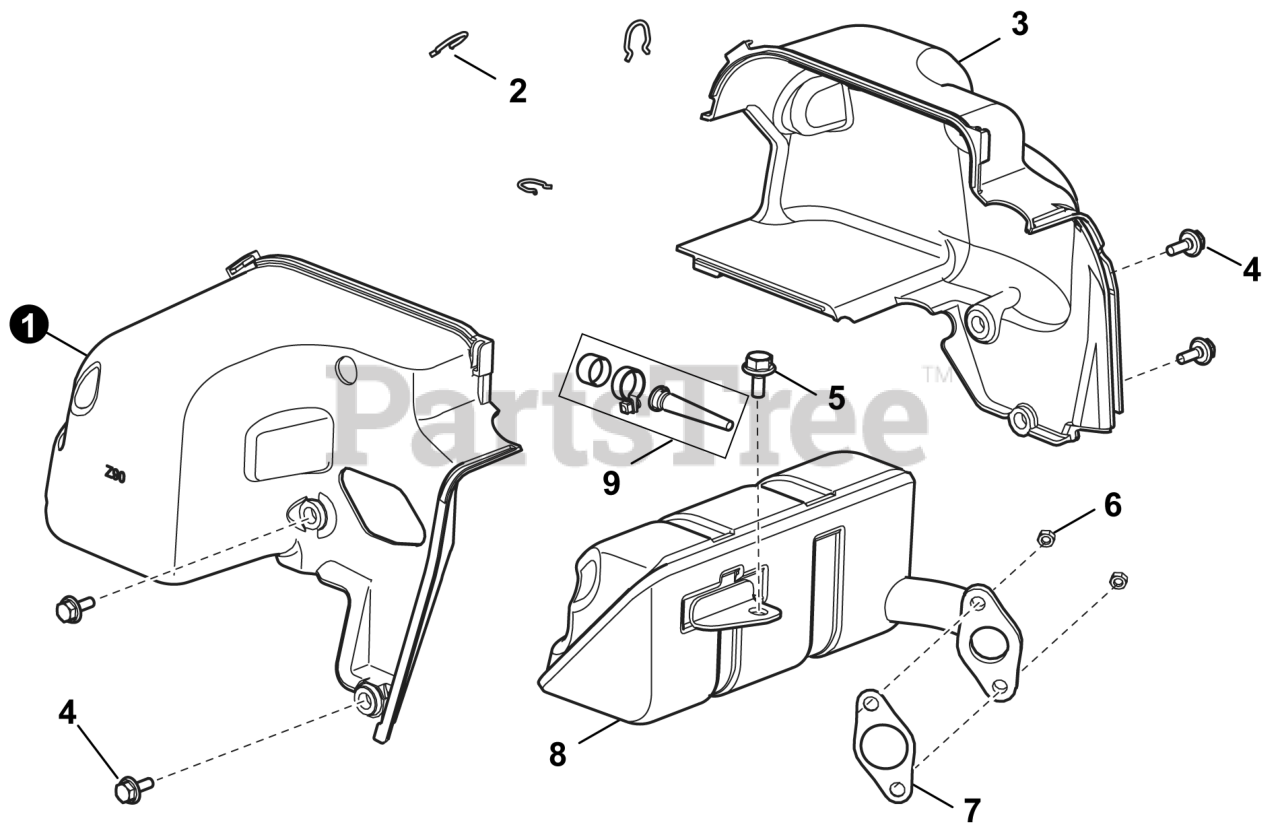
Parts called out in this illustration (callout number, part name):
1	SHROUD, MUFFLER (LEFT)
3	SHROUD, MUFFLER (RIGHT)
7	GASKET, EXHAUST OUTLET
8	MUFFLER ASSY.
9	ARRESTOR, SPARK
